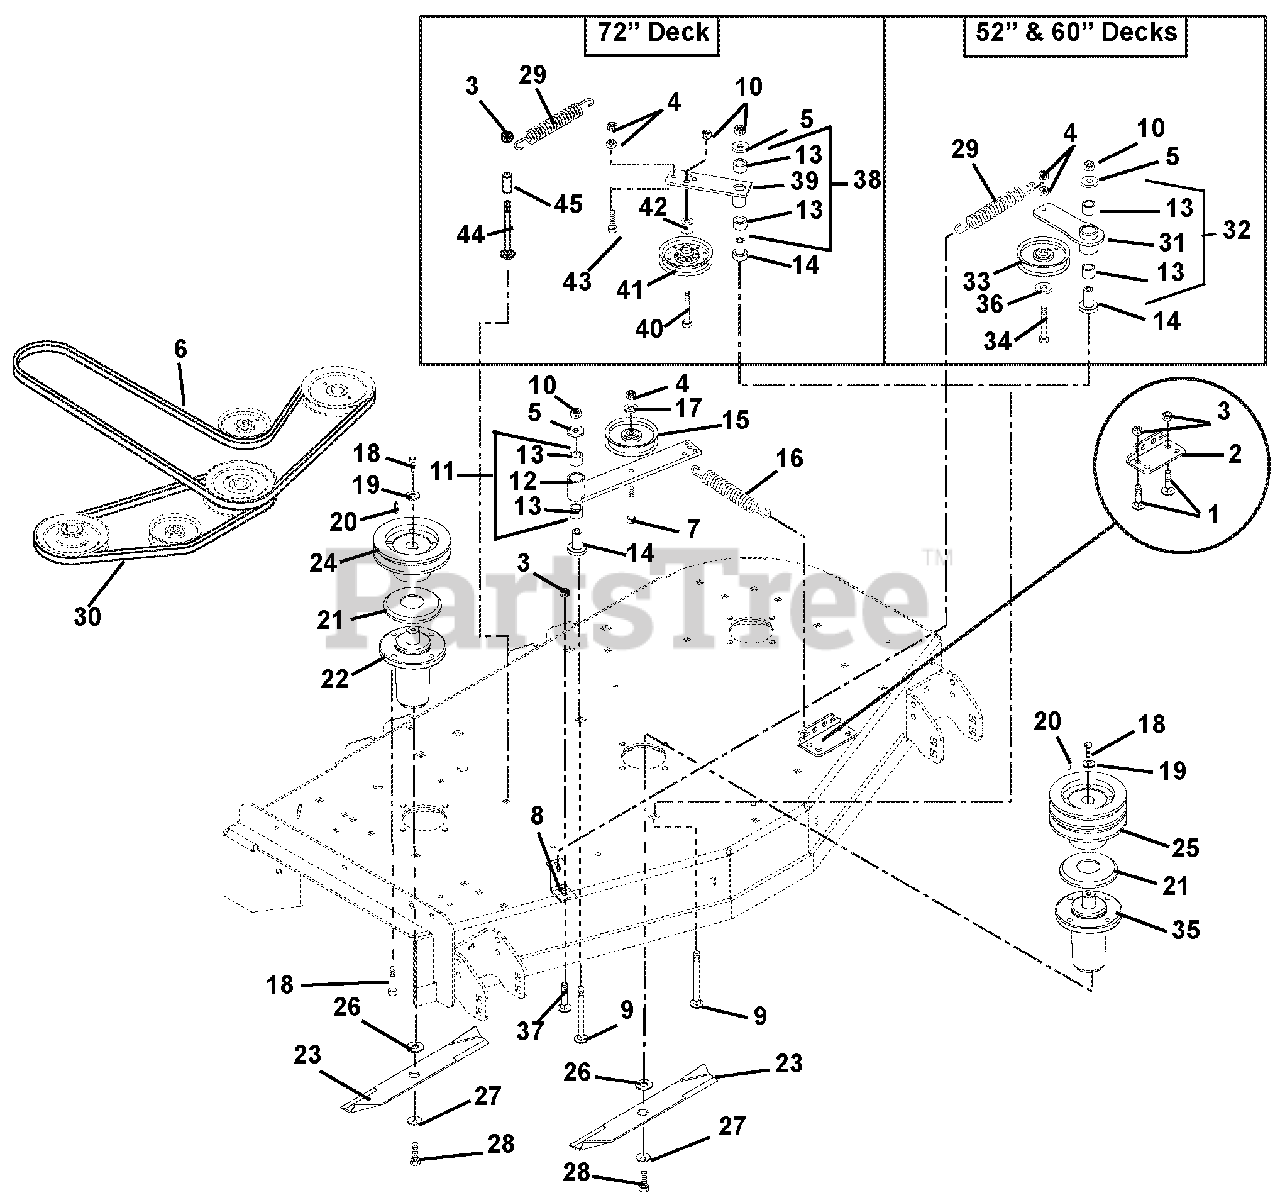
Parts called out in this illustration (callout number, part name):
1	Bolt, Round Head Square Neck .38-16 x .75 Grade 5
2	Bracket, Spring
3	Nut, Locking Top Flange .38-16 (066, 067, 068, 069, 071)
4	Nut, Locking Center .38-16
5	Washer, Flat Steel .531 x 1.25 x .10 (066, 067, 068, 069, 071)
6	V-Belt, B-Section 54.06 x .625 (066, 071)
7	Bolt-Round Head Square Neck .38-16 x 2.75 Grade 5
8	Anchor, Spring
9	Bolt, Round Head Square Neck .50-13 x 3.50 Grade 5
10	Nut, Locking Top Flange .50-13 (066, 067, 068, 069, 071)
11	Assembly, Idler Pivot Arm (Contains Items 12 & 13)
12	Weldment, Idler Pivot Arm
13	Bearing, 1.00 x 1.12 x .75
14	Bearing, Pedestal Powdered Metal
15	Idler, Flat 4.00 x .38 (2.00 W)
16	Spring, Extension
17	Washer, Flat Steel .375 x 1.125 x .065
18	Bolt, Hex .38-16 x 1.00 Grade 8
19	Washer, Flat Steel .406 x 1.50 x .245
20	Key, Square .25 x .25 x 1.00
21	Slinger, Dust
22	Assembly, Maintenance Free Spindle
23	Blade, Mower (070, 072)
24	Weldment, Spindle Sheave 5.00 (066, 071)
25	Sheave, Double (5.25) (066, 071)
26	Washer, Flat .64 x 1.81 x .25
27	Washer, Bellville .63 x 1.625 x .14
28	Bolt, Hex .62-18 x 1.75 Grade 8
29	Spring, Extension
30	V-Belt 5L-Section 49.97 x .672 (070, 072)
31	Arm, Idler Pivot
32	Asm, Idler Pivot Arm (Contains Items 13 and 31)
33	V-Idler, 4.00 x .38
34	Bolt, Hex .38-16 x 2.25 Grade 5
35	Spindle Assembly (Center)
36	Washer, Flat Steel .406 x .812 x .065
37	Bolt, Round Head Square Neck .38-16 x 1.00 Grade 5
38	Assembly, Idler Arm Guard Drive (Includes Items 13 and 39) (070, 072)
39	Weldment, Idler Arm Ground Drive (070, 072)
40	Bolt, Hex .38-16 x 6.00 Grade 5 (070, 072)
41	Idler, Flat Pulley 6.75 x .51 (070, 072)
42	Spacer .513 x .748 x .62 (070, 072)
43	Bolt, Hex .38-16 x 1.25 Grade 5 (070, 072)
44	Bolt, Round Head Square Neck .38-16 x 2.75 Grade 5 (070, 072)
45	Spacer .38 x .625 x 1.50 (070, 072)
